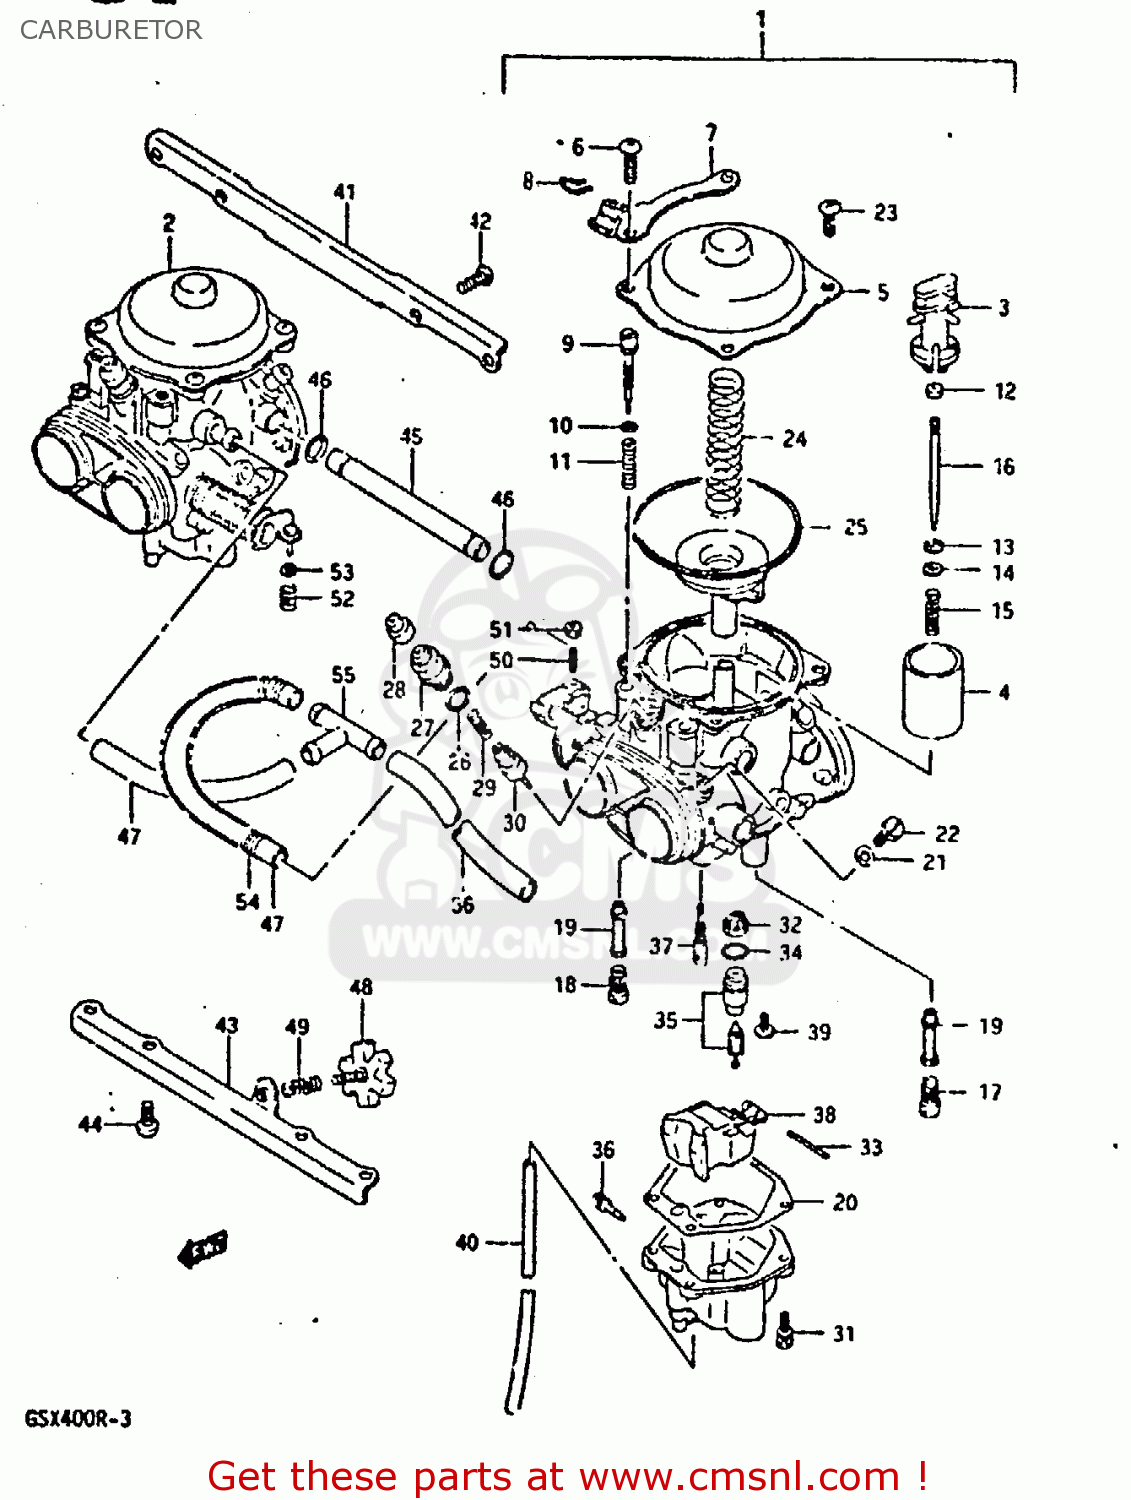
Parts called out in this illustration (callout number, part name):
2	CARBURATEUR
3	HOUDER
4	PLUNJER
6	SCREW
9	ADJUSTER SCREW
10	O-RING
12	RING
13	E-RING
14	SCHOTEL
15	VEER
16	SPROEIERNAALD
17	JET,MAIN(94)
19	NAALDHOUDER
20	GASKET
21	WASHER
23	SCREW
24	SPRING.DIAPHRAG
25	DIAPHRAGM,CARBURETOR
26	O-RING
27	HOLDER,GUIDE
28	CAP
29	SPRING
30	PLUNGER
31	SCREW
32	NET
34	O RING
35	VALVE ASSY,NEEDLE
36	PLUG,DRAIN
37	JET,PILOT(34)
38	FLOAT
39	SCREW
42	SCREW
44	SCREW
46	O RING
47	HOSE
52	SPRING
53	WASHER
55	3-WAY [FILTER TO PUMP)
56	HOSE
